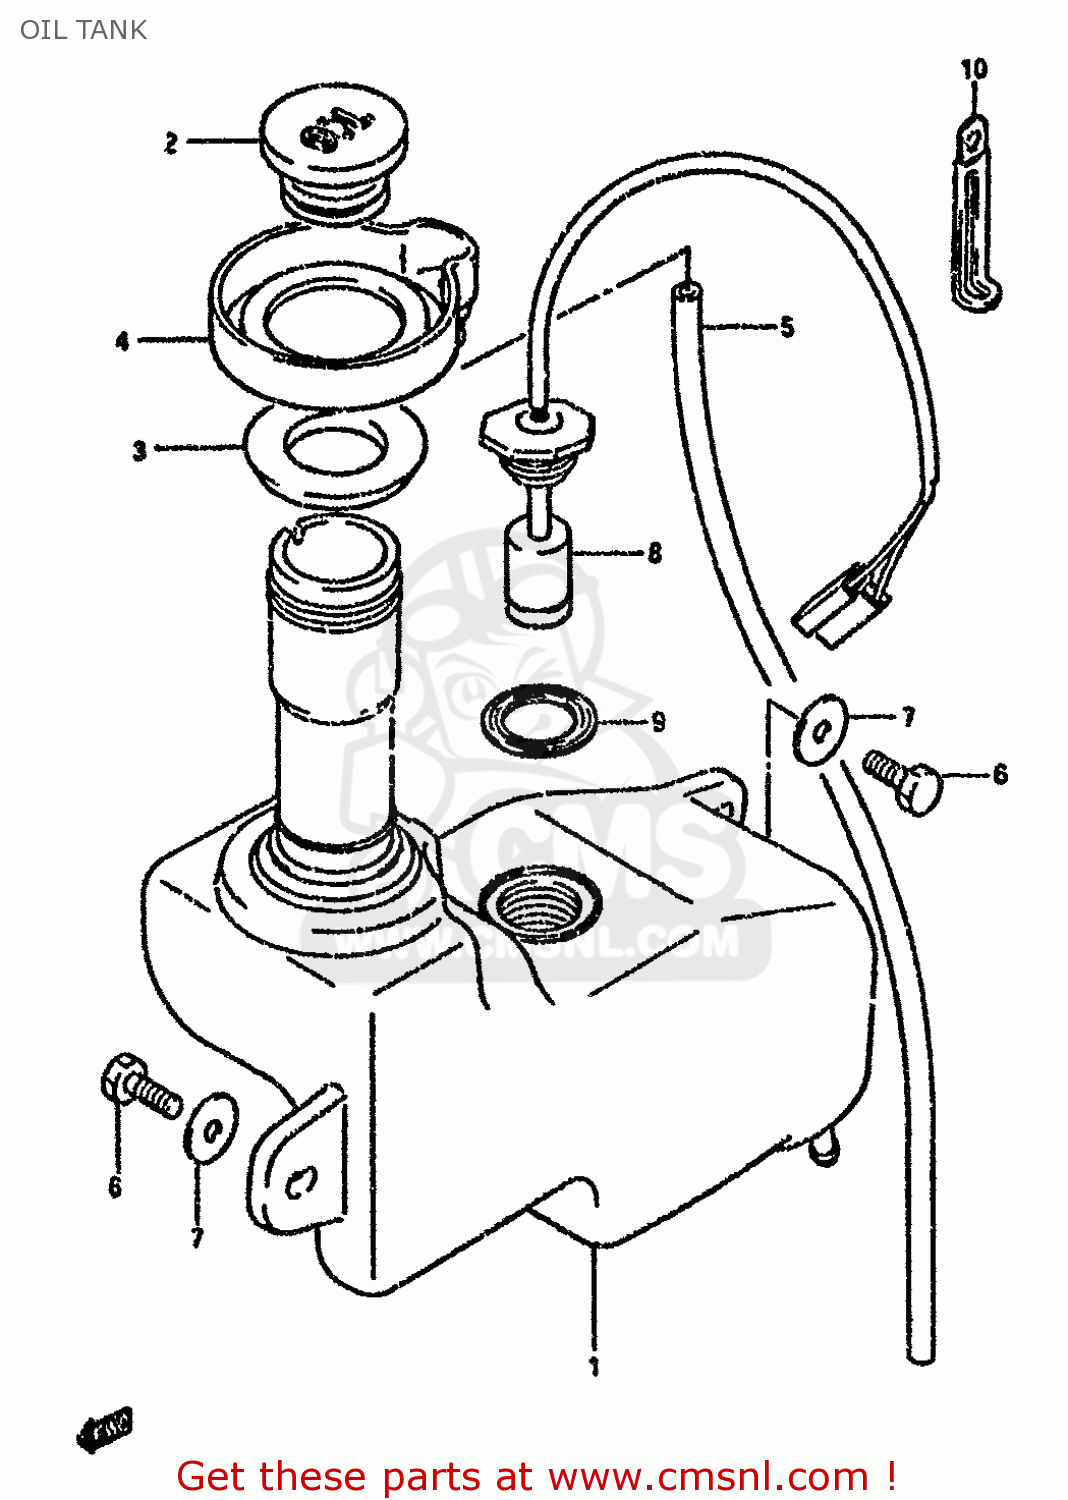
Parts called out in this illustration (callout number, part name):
1	TANK,OIL
2	CAP,OIL TANK
3	CUSHION,OIL TANK
4	TRAY,FUEL & OIL DRAIN
5	HOSE(5X8.2X2000)
6	BOLT
7	WASHER
8	SWITCH ASSY,OIL LEVEL
9	GASKET (NAS)
10	CLAMP(L:45)
